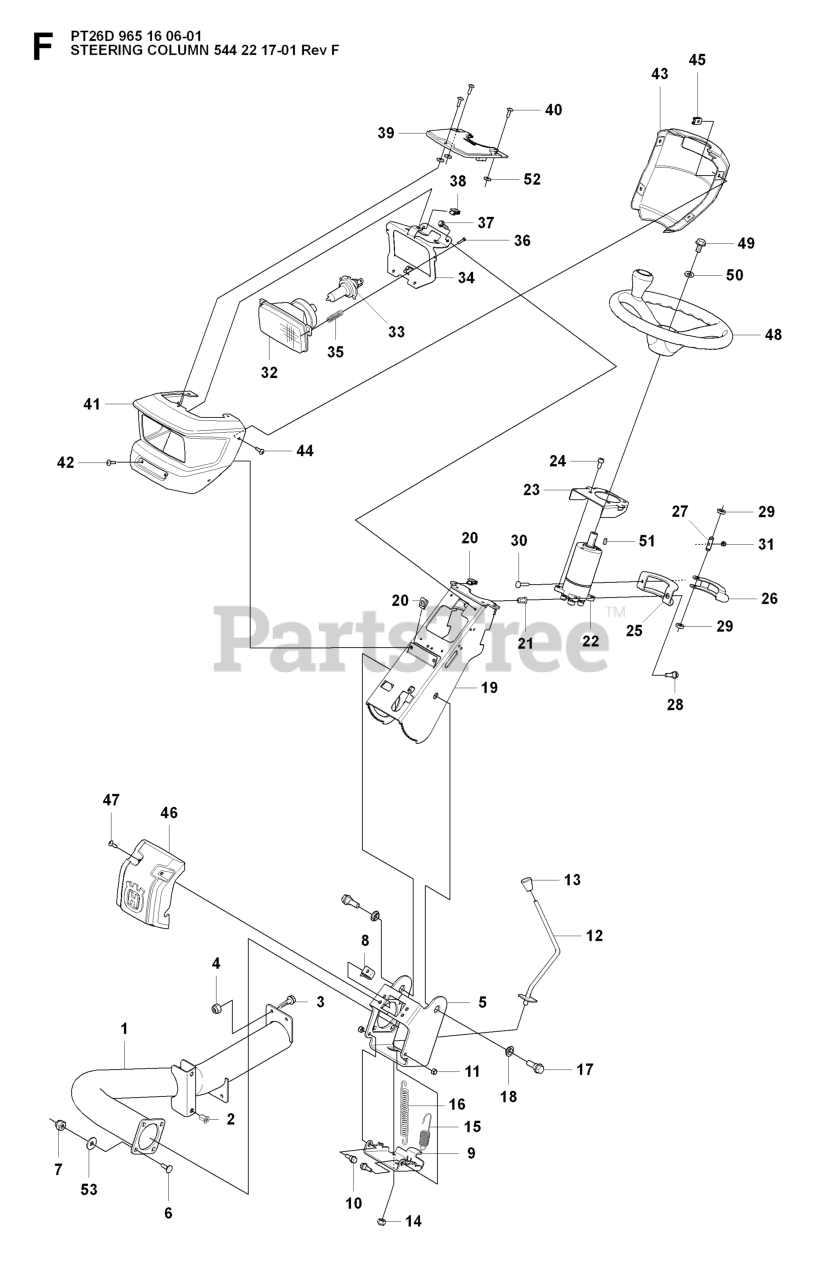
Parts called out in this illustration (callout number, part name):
4	LOCKNUT M8
7	LOCKNUT M8
11	LOCKNUT M8
16	DRAW SPRING L=108
21	BLIND RIVET NUT
31	LOCKNUT M6
49	SCREW EHHFM
53	WASHER BRB 8.4X17
